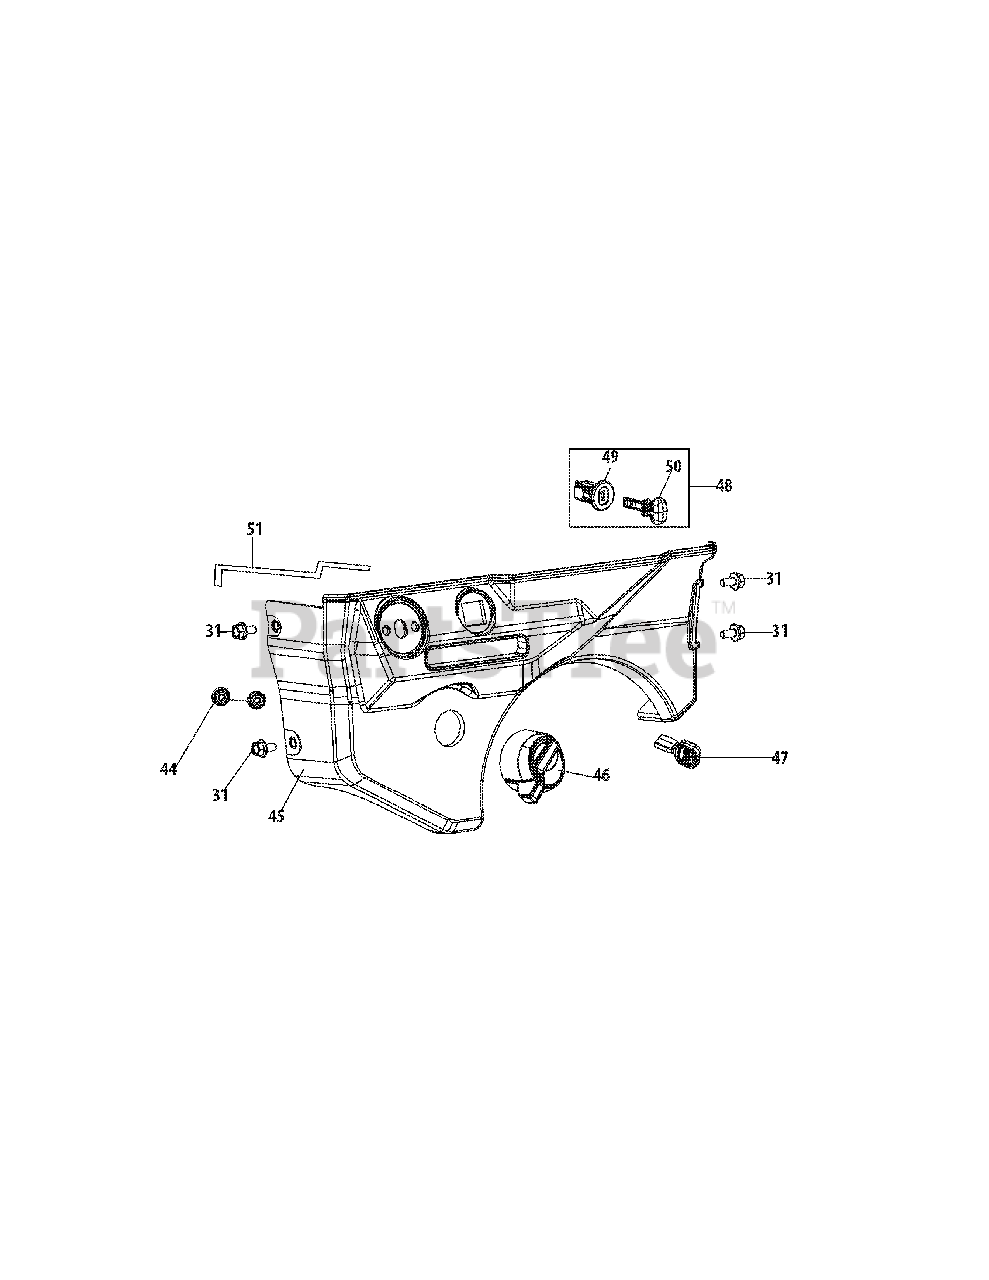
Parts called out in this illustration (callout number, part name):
31	Bolt, M6×12
44	Nut, M6
45	Control Panel
46	Choke Lever
47	Throttle Lever Knob
48	Stop Switch
49	Stop Switch Base
50	Stop Switch Key
51	Choke Linkage
